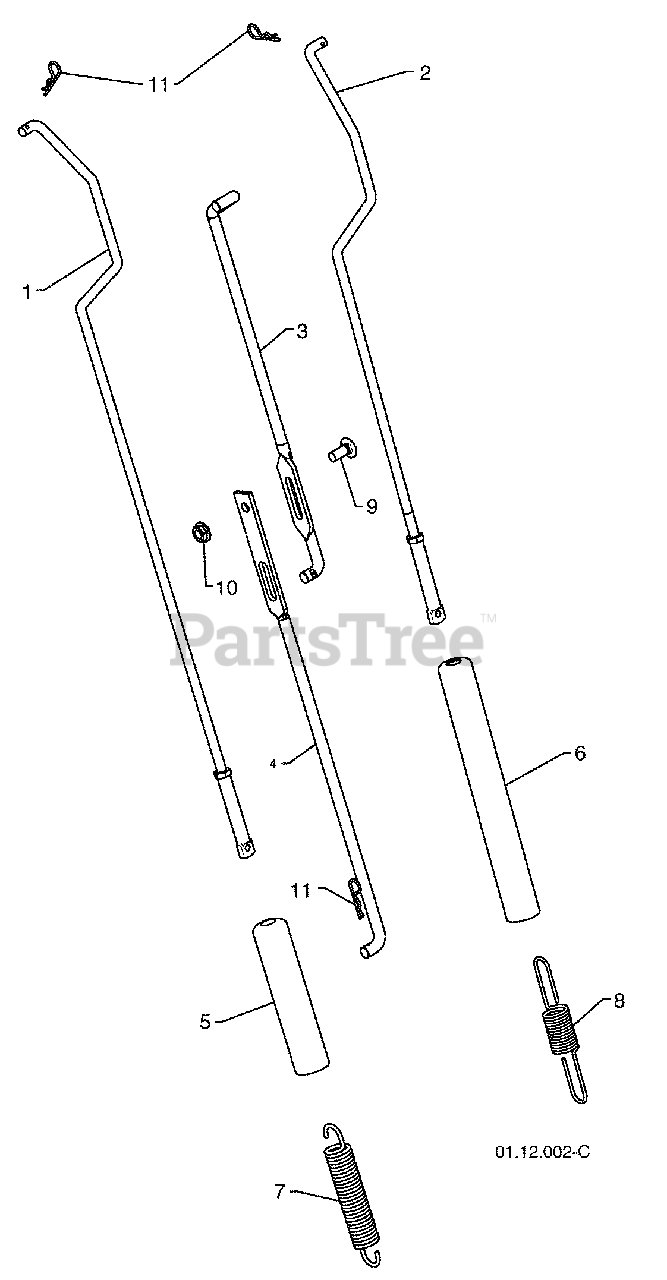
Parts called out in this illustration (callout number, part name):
1	IMPELLER ROD ASSEMBLY
2	TRACTION ROD ASSEMBLY
3	SHIFTER ROD TOP
4	SHIFTER ROD BOTTOM
5	SPRING SLEEVE
6	SPRING SLEEVE
7	IMPELLER SPRING
8	TRACTION SPRING
9	CARRIAGE BOLT 5/16--18 X .625
10	NUT 5/16--18
